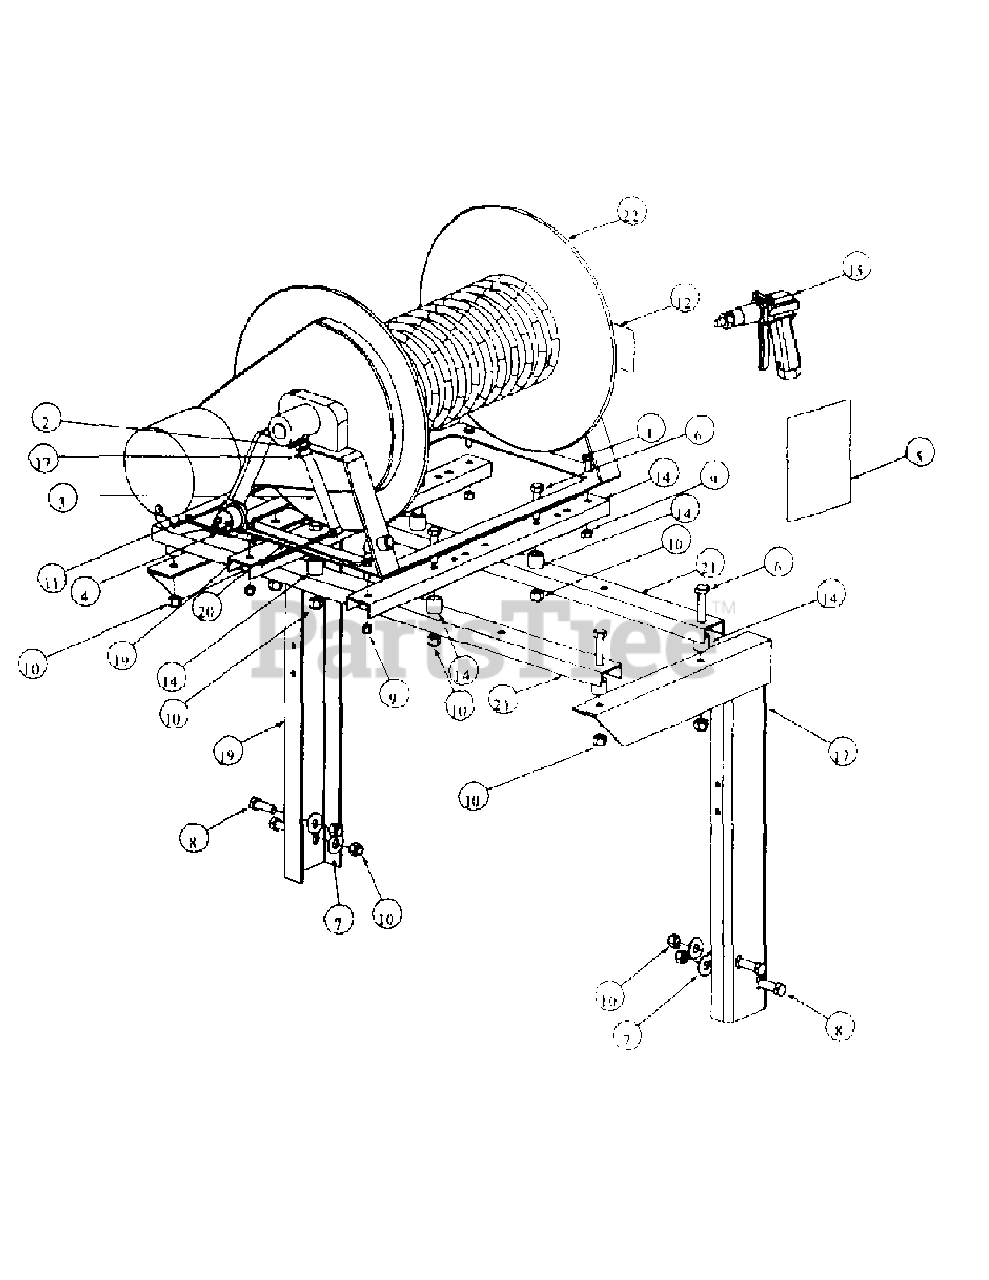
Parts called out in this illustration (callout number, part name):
1	HHCS, 3/8-16 x 1"
2	Hose Barb, 1/2NPT, 1/2
3	Hose, 112" by ft. (sold by the foot)
4	Terminal Ring, 3/8 x #8 Ga
5	Wiring Kit, Elec. Hose Reel
6	HHCS, 112-13, 2.00
7	Flat Washer, 1/2 USS
8	HHCS, 1/2-13, 1-1/2
9	Nut, Lock Nylon Insert, 3/8-16
10	Nut, Lock Nylon lnsert, 1/2-13
11	Cable, Tie, 3/16 x .05 x 7-1/2
12	Decal, Max Hose Length
14	Spacer Crossbar
15	Spray Gun
16	Hose Clamp, 1/2, 7/8
17	Bracket Assembly, RH Hose Reel
18	Bracket Assembly, LH Hose Reel
19	Channel, Pick-Up Mount Reel Support
20	Wiring Harness
21	Crossmember Hose Reel
